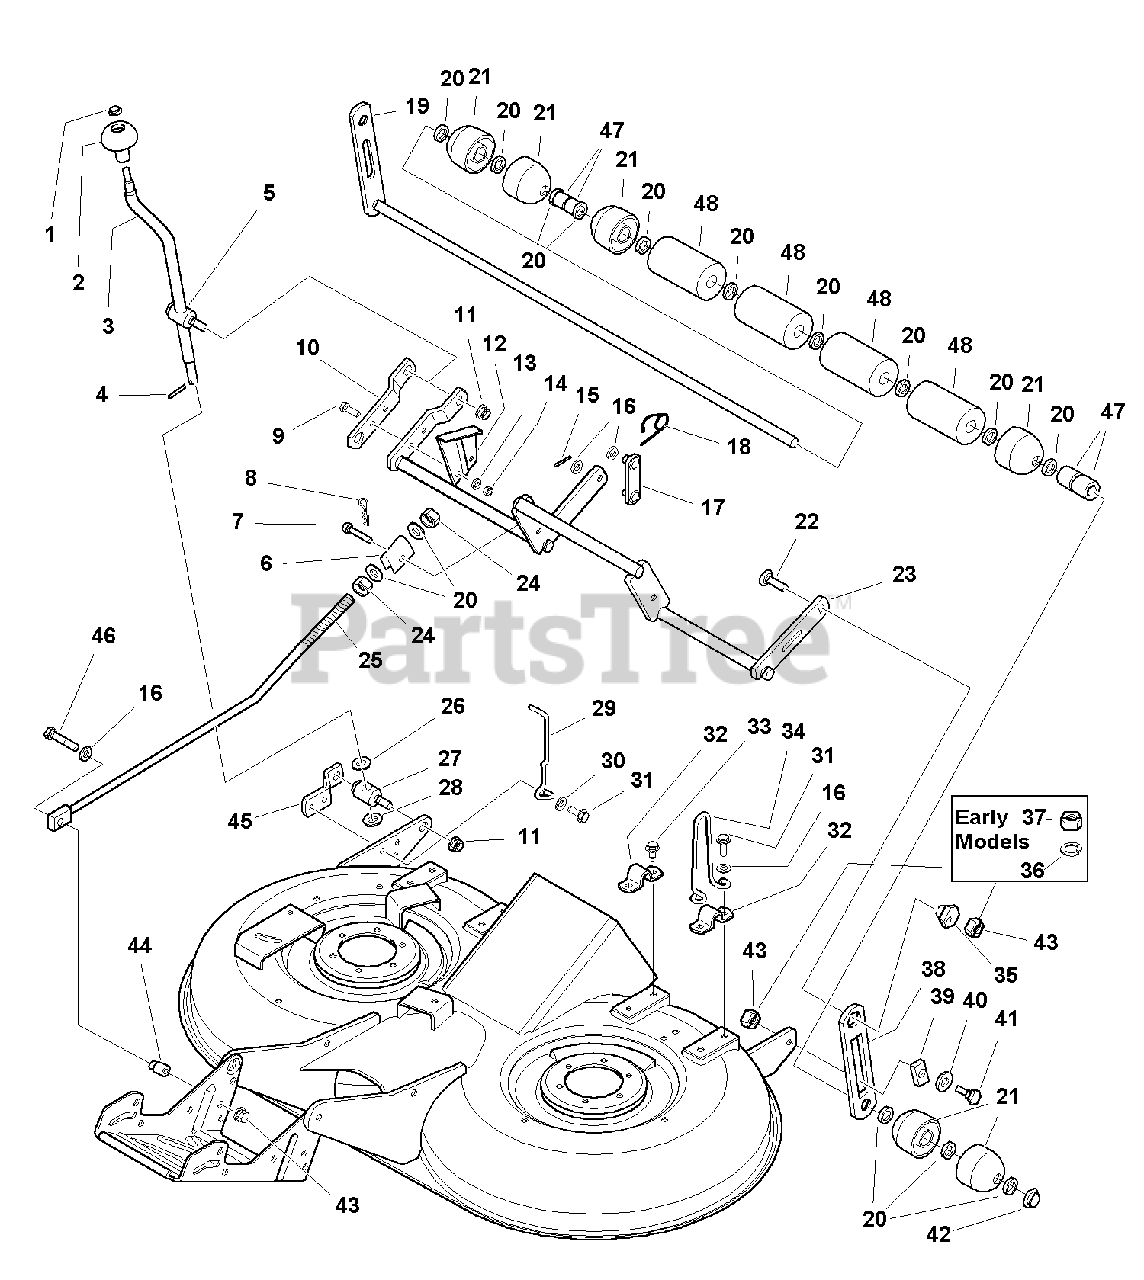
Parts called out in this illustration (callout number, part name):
1	PAL NUT
2	KNOB, Spinner
3	CRANK, Height Adjust
4	PIN, Spring
5	TRUNNION, Rod
6	TRUNNION, Bracket
7	PIN, Round Head, Drilled, 3/8 x 2
8	CLIP, Hair Pin
9	CAPSCREW, Hex Head, 5/16-18 x 1 G8
10	ARM, Rear Adjustable
11	NUT, Hex Flagne Two-Way Lock, 1/2-13
12	BRACKET, Height of Cut
14	NUT, Hex, 5/16-18 Whiz Lock
15	PIN, Cotter
16	WASHER, 3/8
17	LINK & WELD PINS ASSEMBLY, Lower Lift
18	RETAINER, Pin, Spring
19	SHAFT & BAR ASSEMBLY, Roller
20	WASHER, 5/8
22	CARRIAGE BOLT, 3/8-16 x 1-1/2
23	SHAFT & ARMS ASSEMBLY, 40" Rear
24	NUT, Hex, 5/8-11
25	ROD, Adjustment
26	WASHER, 1/2
27	TRUNNION, Threaded
28	WASHER, Detent
29	INDICATOR, Height of Cut
30	WASHER, 5/16
31	CAPSCREW, Hex Washer Head, Taptite, 5/16-18 x 1
32	STRAP, Roller Support
33	CAPSCREW, Hex Washer Head, Taptite, 5/16-18 x 3/4
34	STOP, Up Wire
35	NUT, Hex Adjusting, .99 DIA .687
36	LOCKWASHER, 3/4 (Early Models)
37	NUT, Hex, 3/8-16 (Early Models)
38	BAR, Roller
39	SLIDE, Roller
40	WASHER, 1/2
41	BOLT, Shoulder, 3/8-16 X 1.34
42	NUT, Push On
43	NUT, Hex Lock Alum Insert, 3/8-16 (Later Models)
45	STRAP, Trunnion Retainer
46	CAPSCREW, Hex Head, 3/8-16 x 1-3/4
